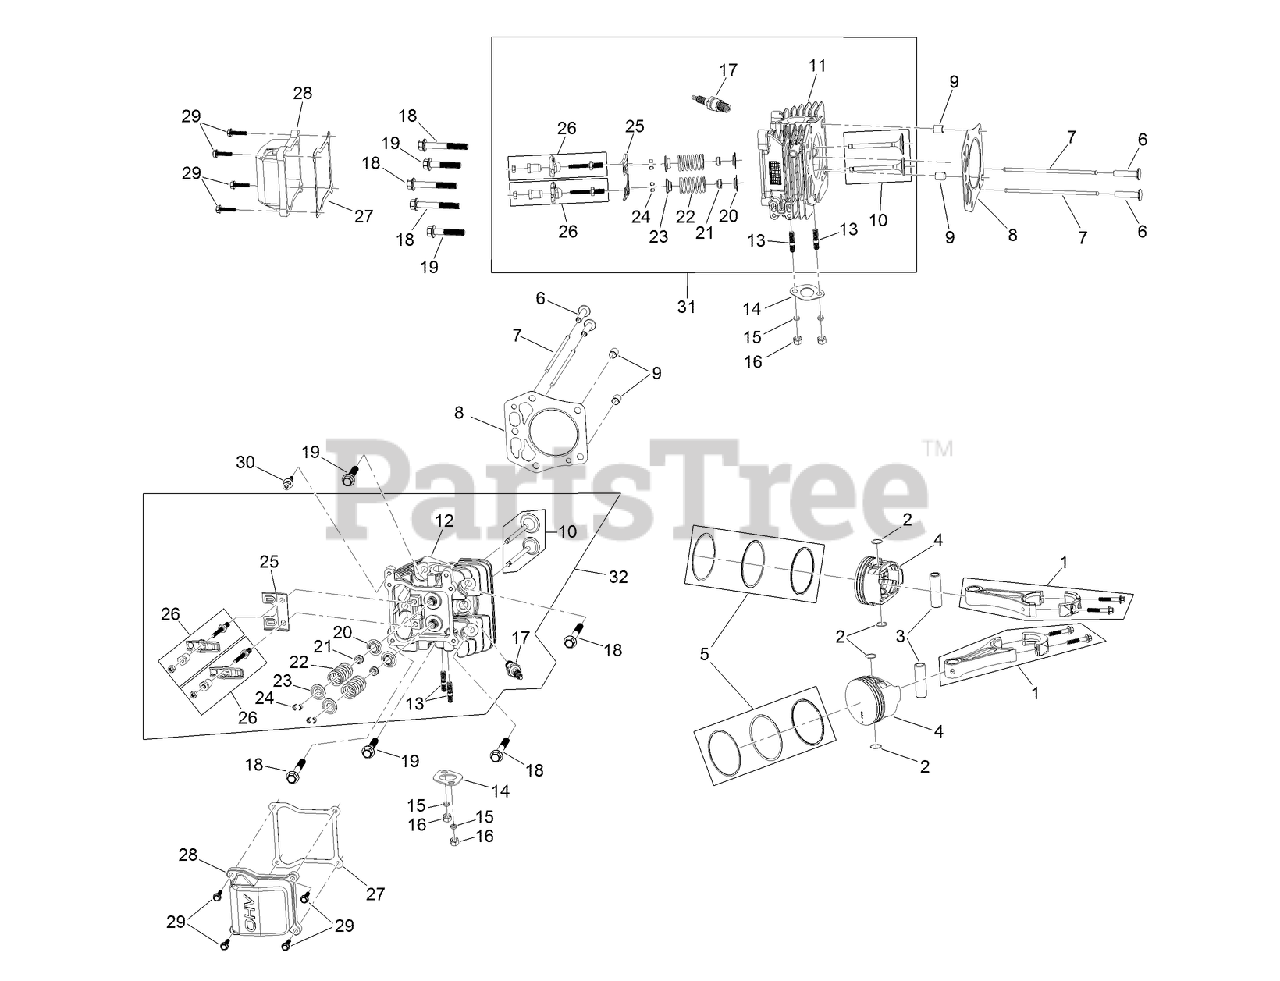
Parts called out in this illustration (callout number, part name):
1	CONNECTING ROD ASM
2	CLIP-PIN, PISTON
3	PIN-PISTON
4	PISTON
5	PISTON RING SET
6	LIFTER-VALVE
7	ROD-PUSH
8	GASKET-HEAD, CYLINDER
9	PIN-DOWEL
10	VALVE SET
11	HEAD-CYLINDER, RIGHT
12	HEAD-CYLINDER, LEFT
13	STUD-EXHAUST
14	GASKET-EXHAUST
15	WASHER-LOCK, SPLIT
16	NUT-HH
17	SPARK PLUG
18	SCREW-HWH
19	SCREW-HWH
20	SEAT-SPRING, VALVE
21	SEAL-STEM, VALVE
22	SPRING-VALVE
23	RETAINER-SPRING, VALVE
24	KEEPER-VALVE
25	PLATE-GUIDE, PUSH ROD
27	GASKET-VALVE COVER
28	COVER-VALVE
29	SCREW-HHF
30	SCREW-SHOULDER, HH
